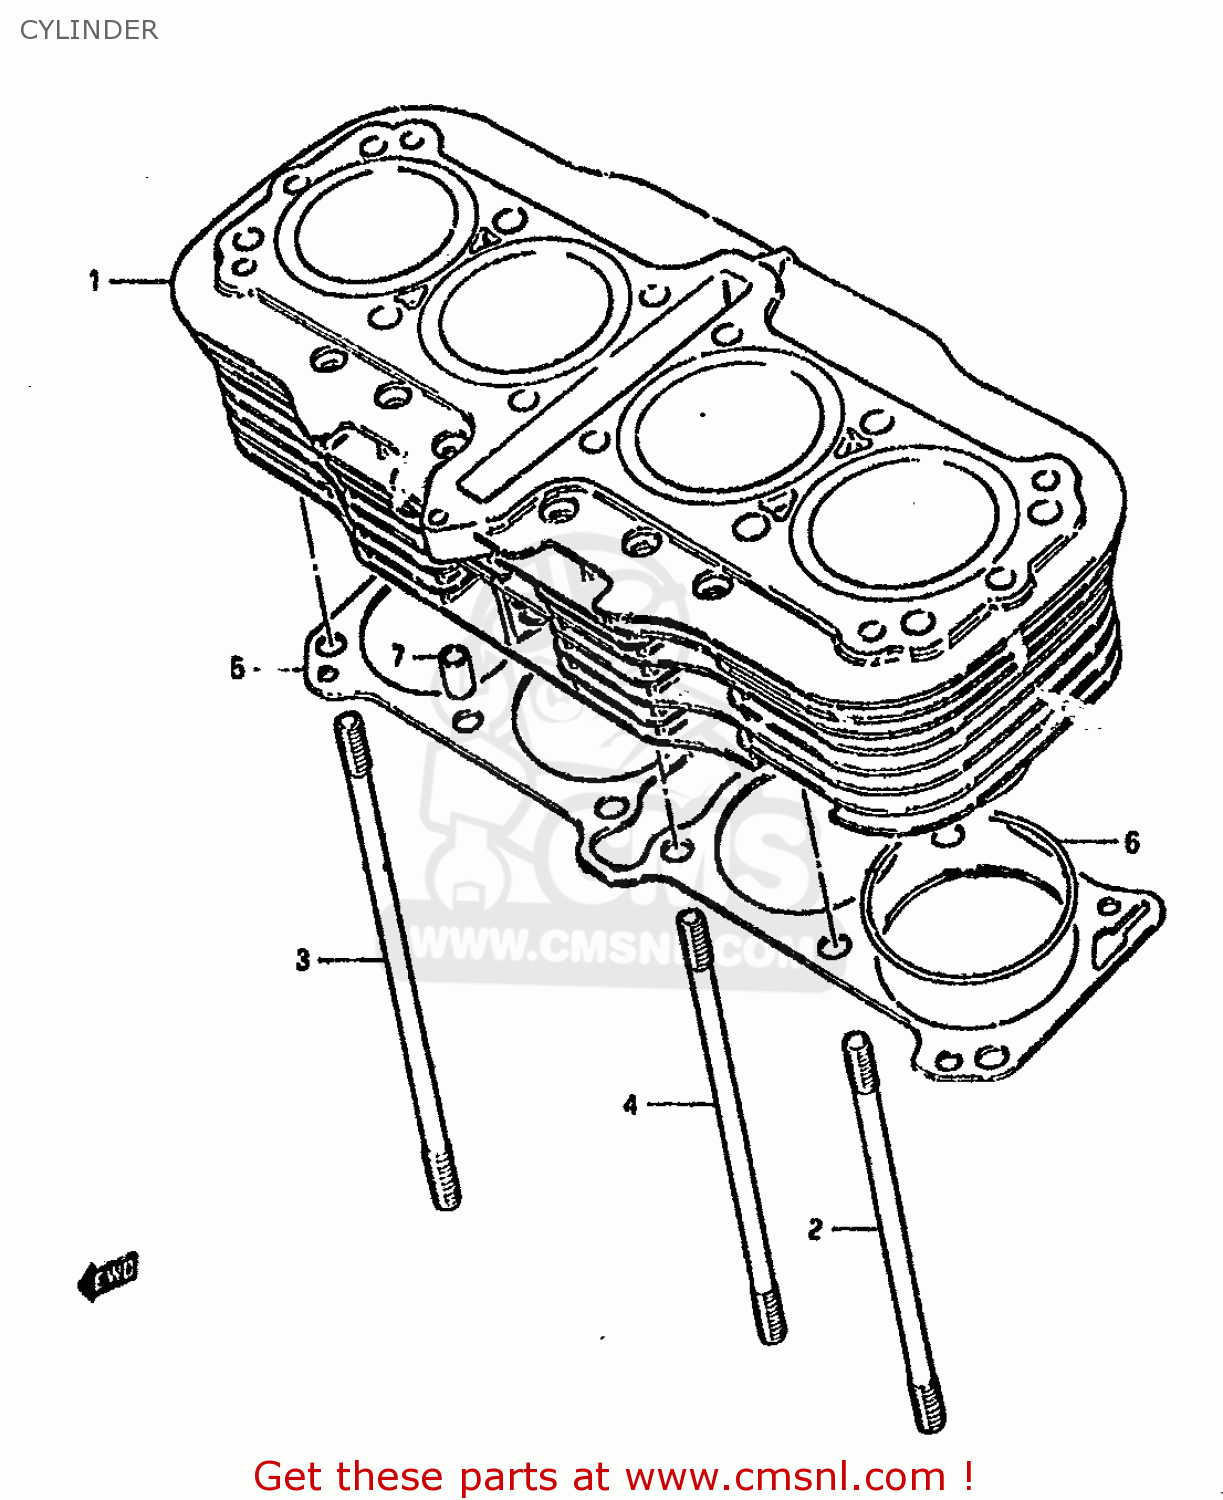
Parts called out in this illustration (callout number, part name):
1	CYLINDER
2	STUD
3	STUD
4	STUD
5	GASKET,CYLINDER (MCA)
6	O RING(D:2,ID:70)
7	PIN
